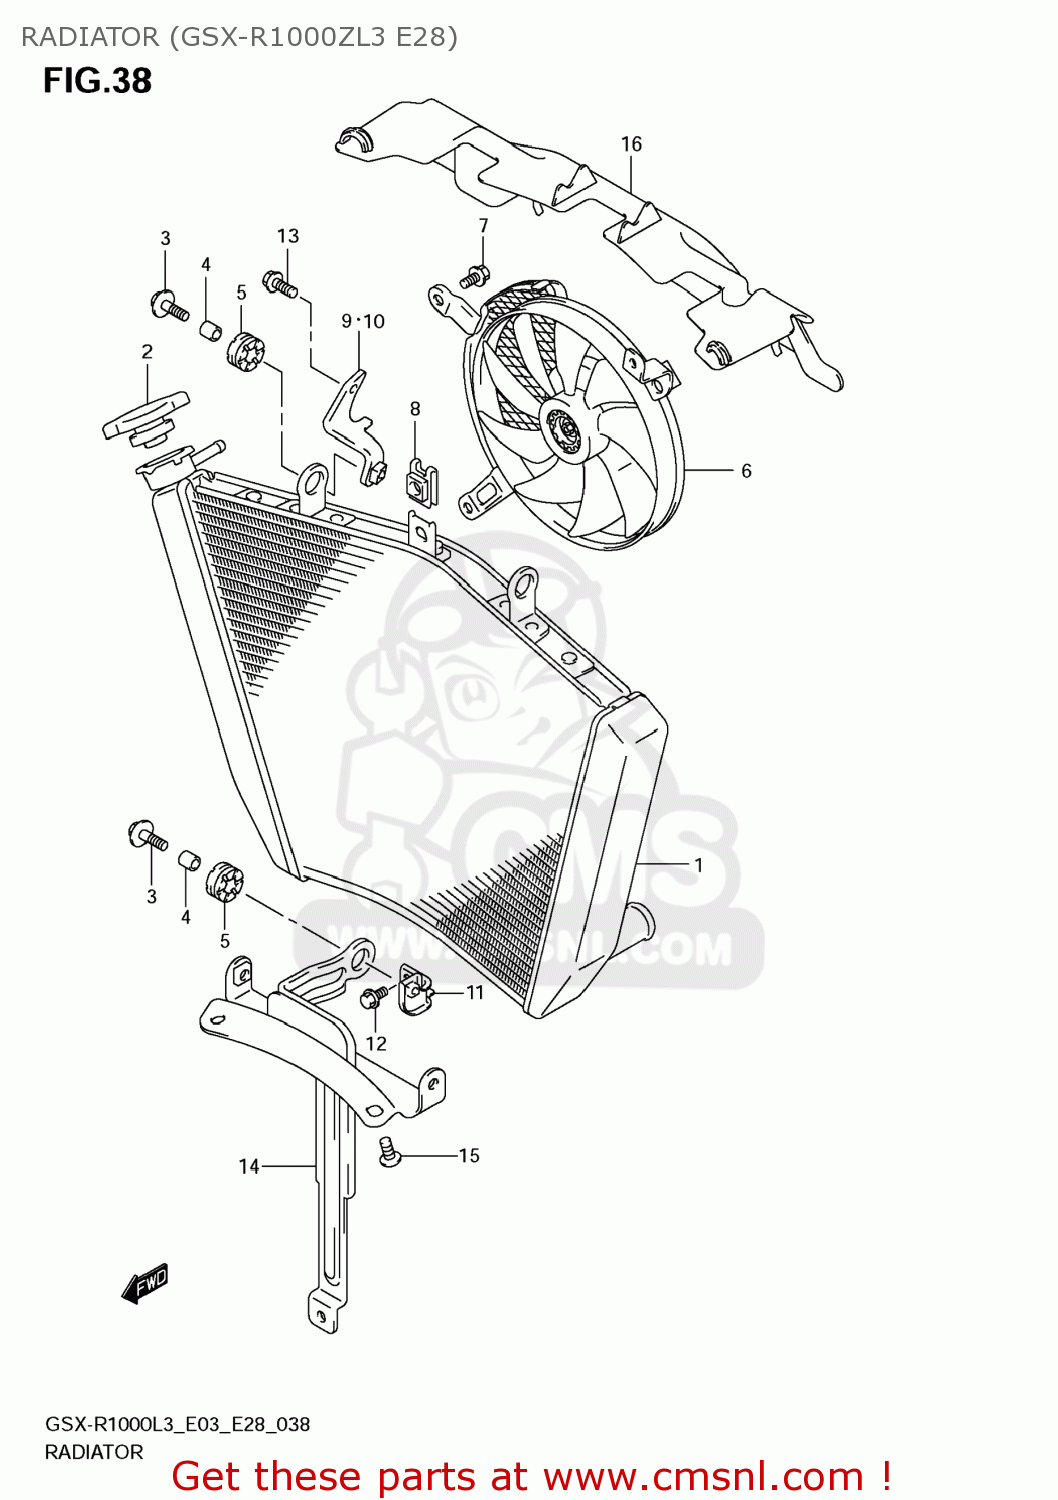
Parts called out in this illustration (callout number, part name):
1	RADIATOR ASSY,WATER
2	CAP,RADIATOR
3	BOLT(6X25)
4	SPACER(6.5X10X12)
5	CUSHION
6	FAN ASSY,RADIATOR
7	BOLT,FAN ASSY
8	NUT,FAN ASSY
9	BRACKET,RADIATOR,R
10	BRACKET,RADIATOR,L
11	BRACKET,RDTR & OIL COOLER
12	BOLT
13	BOLT
14	BRACKET,RADIATOR SUPPORT
15	BOLT(6X10)
16	SHIELD,RADIATOR HEAT
